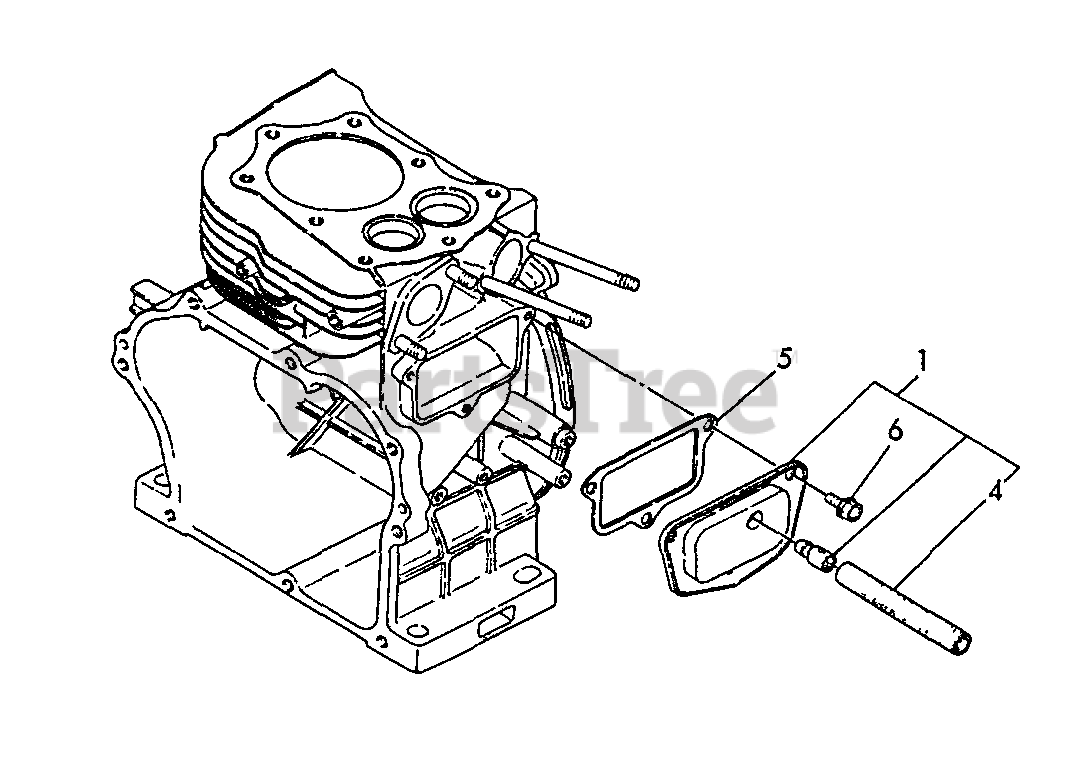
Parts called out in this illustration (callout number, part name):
1	VENT, FUEL TANK
4	PIPE - BREATHER
5	GASKET, BREATHER
6	BOLT - 6X8 -- PLATED
